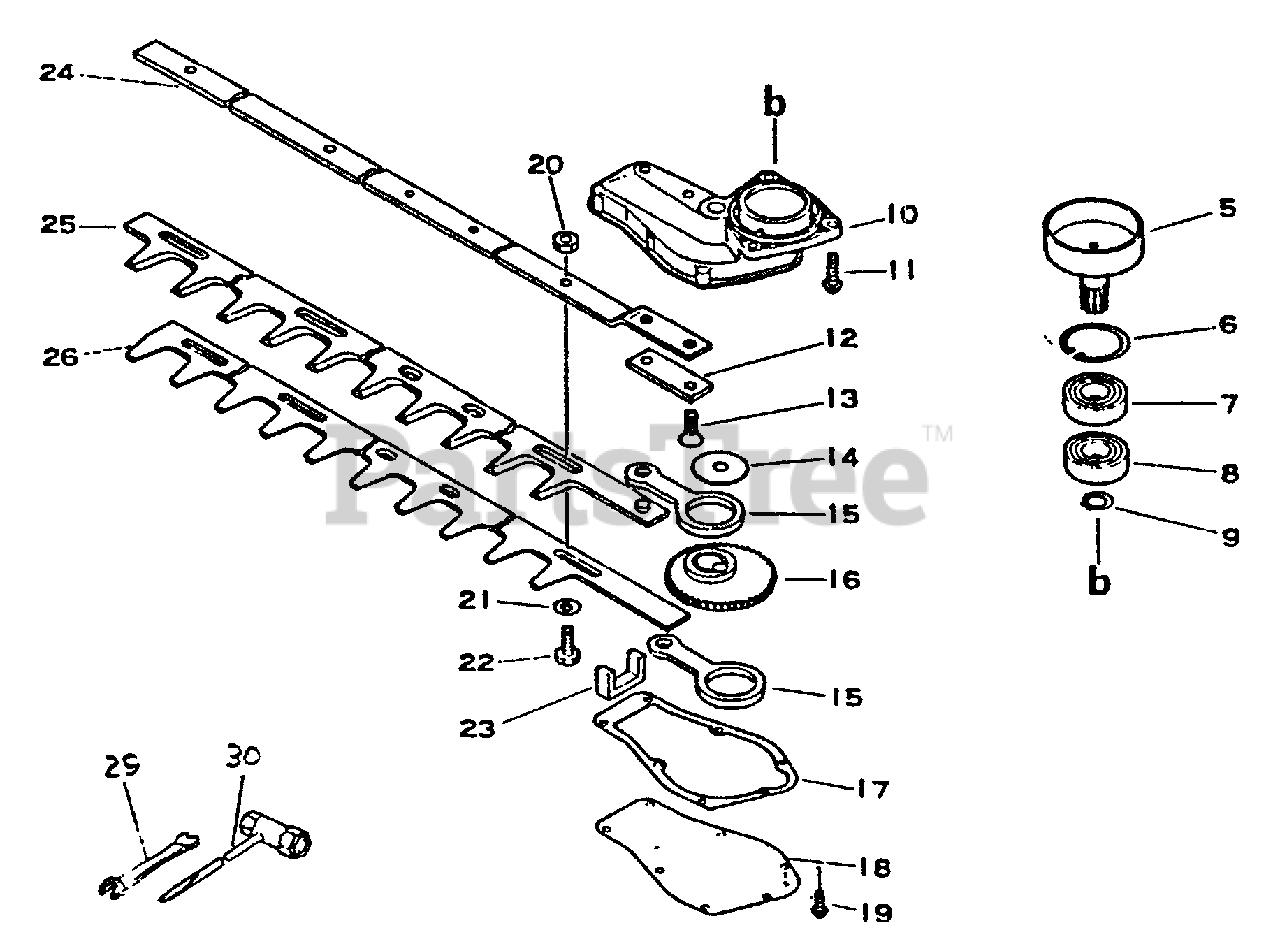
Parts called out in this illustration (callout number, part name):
5	DRUM, CLUTCH
6	RING, RETAINING - 35
7	BEARING, BALL - 6202
8	BEARING, BALL - 6202
9	RING, RETAINING - 14
10	CASE, GEAR
11	SCREW - 5X20
13	SCREW - 6X18
15	ROD, CONNECTING
16	GEAR - DRIVE
17	GASKET, GEAR CASE
18	LID, GEAR CASE
19	SCREW - 4X10
20	LOCKNUT - 6
21	WASHER - 6
23	SEAL, FELT
24	SUPPORT, BLADE
25	BLADE - UPPER
26	BLADE - LOWER
29	SPANNER - 8X10mm
30	T-WRENCH - 13X19mm
